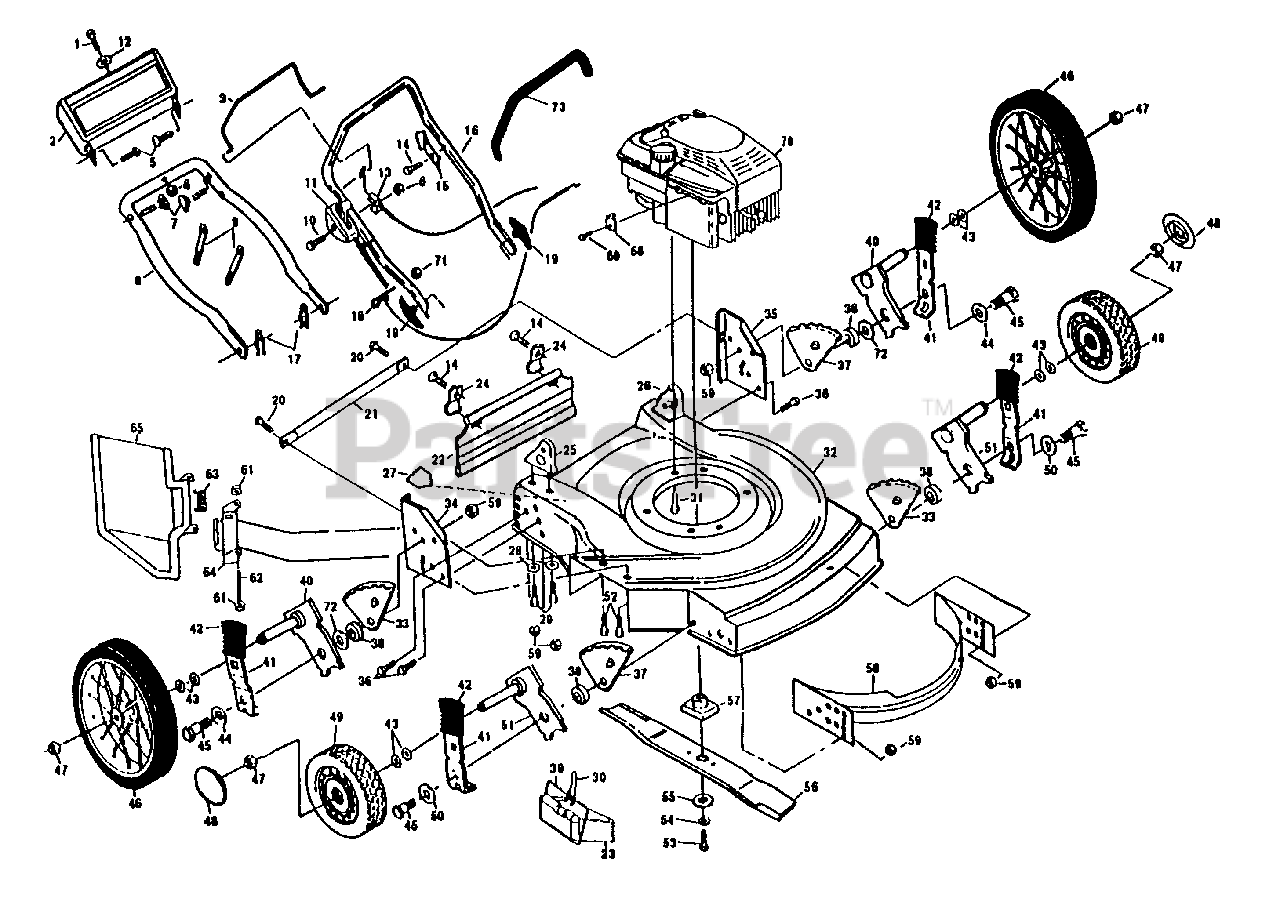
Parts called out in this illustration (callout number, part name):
1	Hex Head Washer Screw 1/4-20 x 1-1/2
2	Trim Plate
3	Control Bar
5	Self-tapping Screw #10-24 x 5/8
6	Locknut 1/4-20
7	Handle Bolt 5/16-18 x 1-3/4
8	Lower Handle
9	Wire Tie
10	Hex Washer Head Screw 1/4-20 x 2.12
11	Throttle Control
13	Engine Zone Control Cable
14	Hex Washer Head Screw #10-24 x 1/2
15	Up-Stop Bracket
16	Upper Handle
17	Hairpin Cotter
18	Rope Guide
19	Handle Knob
20	Self-tapping Screw 1/4-20 x 1/2
21	Support Rod
22	Rear Skirt
23	Mulching Plug
24	Skirt Bracket
25	Handle Bracket Assembly (Right)
26	Handle Bracket Assembly (Left)
27	Danger Decal
29	Thread Cutting Screw 5/16-18 x 1-3/4
30	Mulcher Plug Latch
31	Thread Rolling Screw 3/8-16 x 1
32	Lawn Mower Housing
33	Wheel Adjusting Bracket (LF/RR)
34	Wheel Support Bracket (Right)
35	Wheel Support Bracket (Left)
36	Hex Head Bolt 3/8-16 x 3/4
37	Wheel Adjusting Bracket (RF/LR)
38	Spacer
39	Mulcher Plug Bail
40	Axle Arm Assembly (Rear)
41	Selector Spring
42	Selector Knob
43	Washer
44	Washer
45	Shoulder Bolt 3/8-16
46	Wheel & Tire Assembly
47	Locknut
49	Wheel & Tire Assembly
51	Axle Arm Assembly (Front)
52	Hex W/Sems 1/4-20 x 3/8 Screw
53	Hex Head Screw 3/8-24 x 1-3/8 Gr. 8
54	Helical Washer 3/8
55	Hardened Washer
57	Blade Adapter
58	Front Baffle & Rear
59	Locknut 3/8-16
62	Hinge Rod
63	Torsion Spring
64	Housing Bracket Assembly
65	Discharge Guard
68	Cable Clamp
69	Thread Rolling Screw #10-32 x 5/8
70	Engine - Briggs & Stratton
71	Locknut, Keps 1/4-20
72	Flat Washer 3/8
73	Handle Grip, Foam
